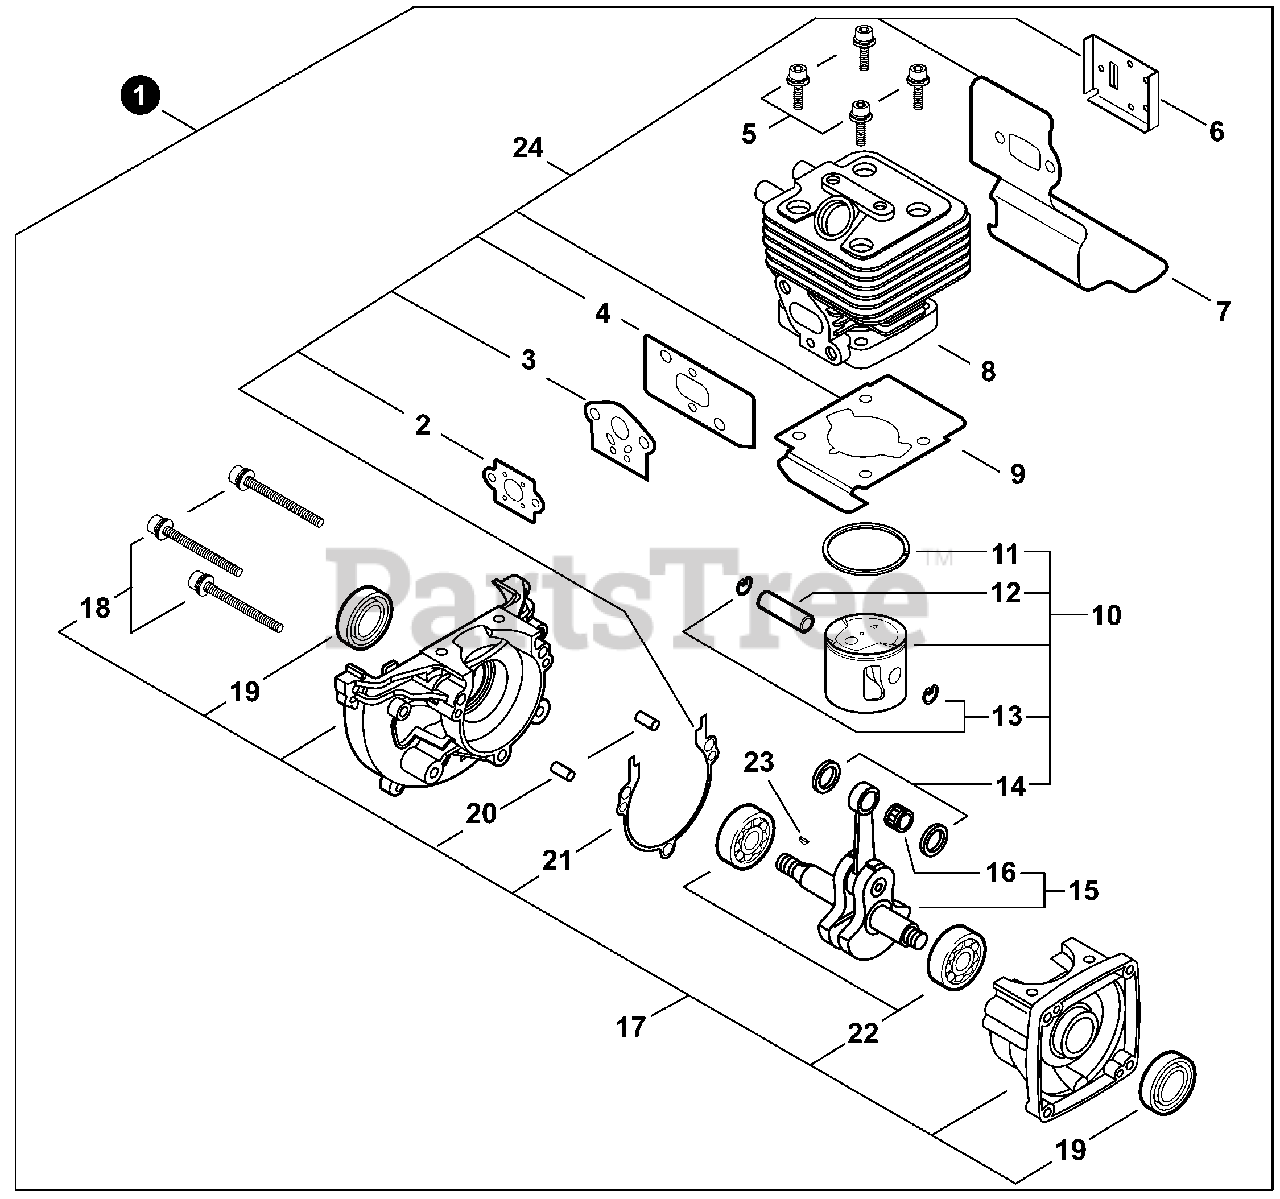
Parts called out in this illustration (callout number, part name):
1	SHORT BLOCK
2	GASKET, INTAKE
3	GASKET, CARBURETOR
4	GASKET, INTAKE
5	BOLT 5×25
6	GASKET, EXHAUST
7	HEAT SHIELD, EXHAUST
8	CYLINDER
9	GASKET, CYLINDER
10	PISTON KIT
11	RING, PISTON
12	PIN, PISTON 5×8×28
13	RING, SNAP
14	WASHER, THRUST 8.2×13×0.5
15	CRANKSHAFT ASSY
16	BEARING, NEEDLE 8
17	CRANKCASE KIT
18	BOLT 5×28
19	SEAL, OIL 12
20	PIN, LOCATING 4×8
21	GASKET, CRANKCASE
22	BEARING, BALL 6201
23	KEY, WOODRUFF
24	GASKET KIT
